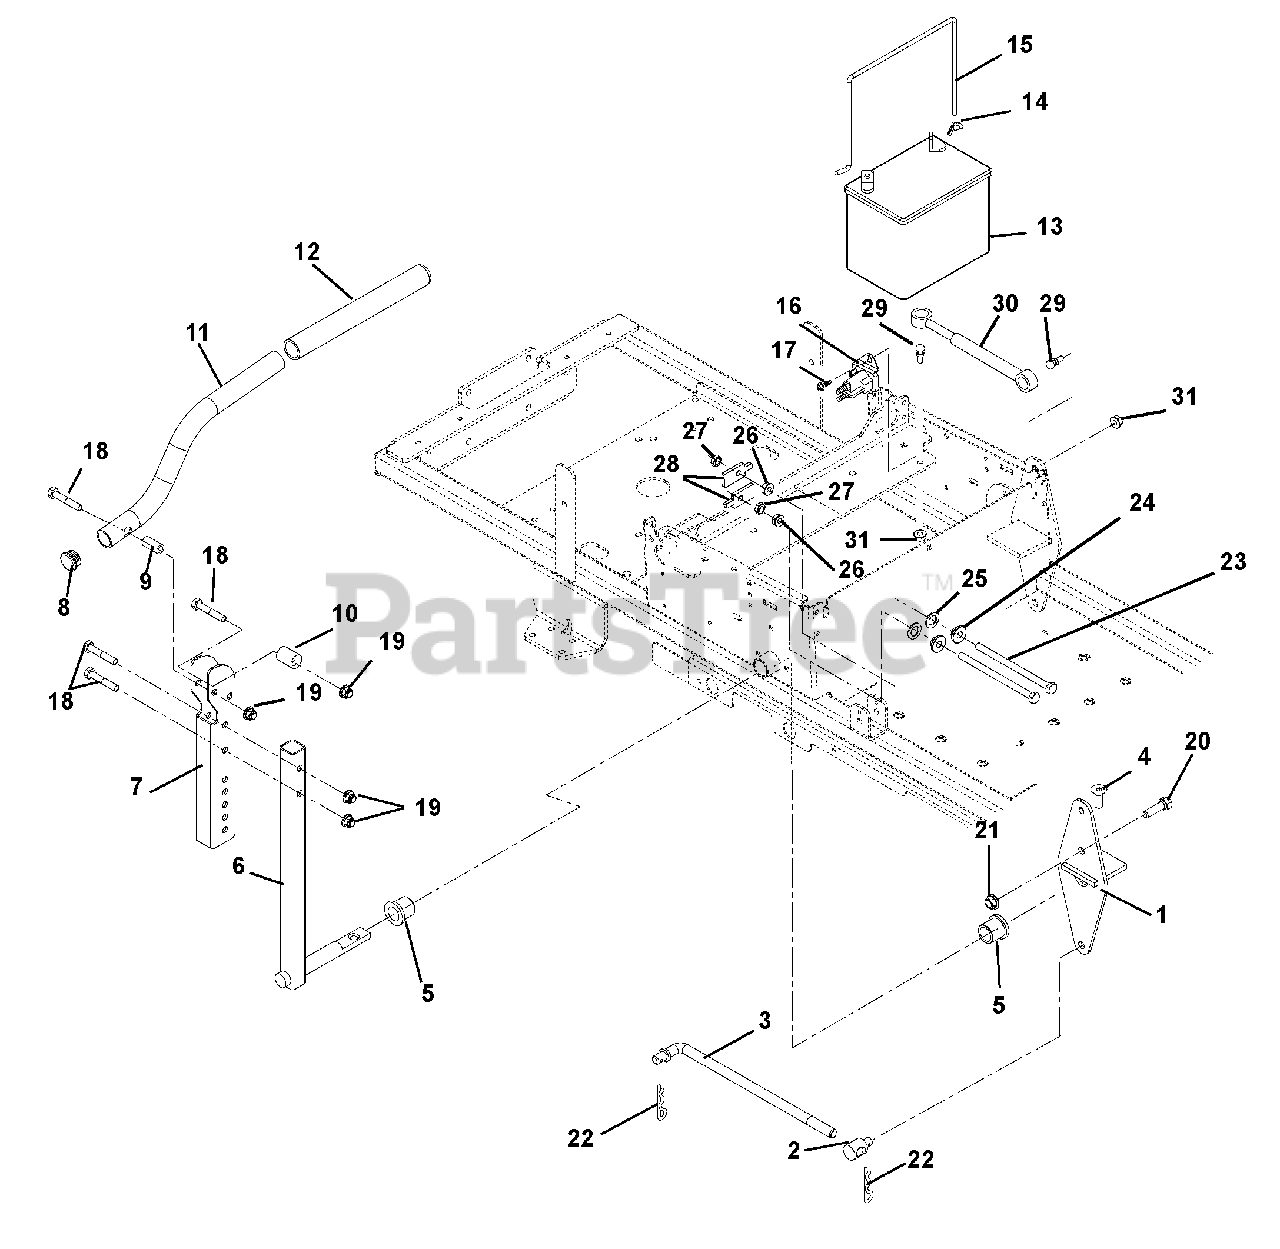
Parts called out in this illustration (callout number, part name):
1	CONTROL LINK WELDMENT
2	PIVOT, ROD (TRUNNION ) .50
3	LINK,WIREFORM
4	BOLT, 3/8-16X1 FSHCS PLN
5	BUSHING-1"X.75"X1"
6	WELDMENT, CONTROL ARM
7	CHANNEL, UPPER HANDLEBAR
8	CAPLUG, HANDLEBAR
9	BSHG, SPCR .330X.500X1.01 PM
10	BSHG,ECCEN .328X.750X1.01 PM
11	HANDLE BAR
12	GRIP - HANDLEBAR
13	Battery, Exide Sealed Maintenance Free U1-250 (Purchase replacement locally)
14	NUT-LK WING .250-20 YWZC
15	BATTERY ROD
16	SOLENOID, HP RTV
17	@SCR-TAP .25-20X.37 HWH YWZ TR
18	@BLT-HEX .31-18X1.75 GR5 YWZC
19	@NUT-LK-NYL-FLG .31-18 YWZC
20	@BLT-HEX .38-16X1.25 GR5 YWZC
21	NUT-HEX-JAM .375-16 YWZC
22	PIN-HAIR INT .08X.18X1.18 YWZC
23	BLT-HEX,5/16-18X5 G2 HH YWZC
24	BSHG-FLG .32X.500X.344X.880
25	WSHR-FL-STL .52X.827X.062 YWZC
26	@NUT-SPNLK-FLG .312-18 YWZC
27	NUT- JAM .312-18 YWZC
28	STOP TAB
29	STUD- BALL
30	DAMPER, CONTROL
31	@NUT-LK-TOP-FLG .31-18 YWZC
